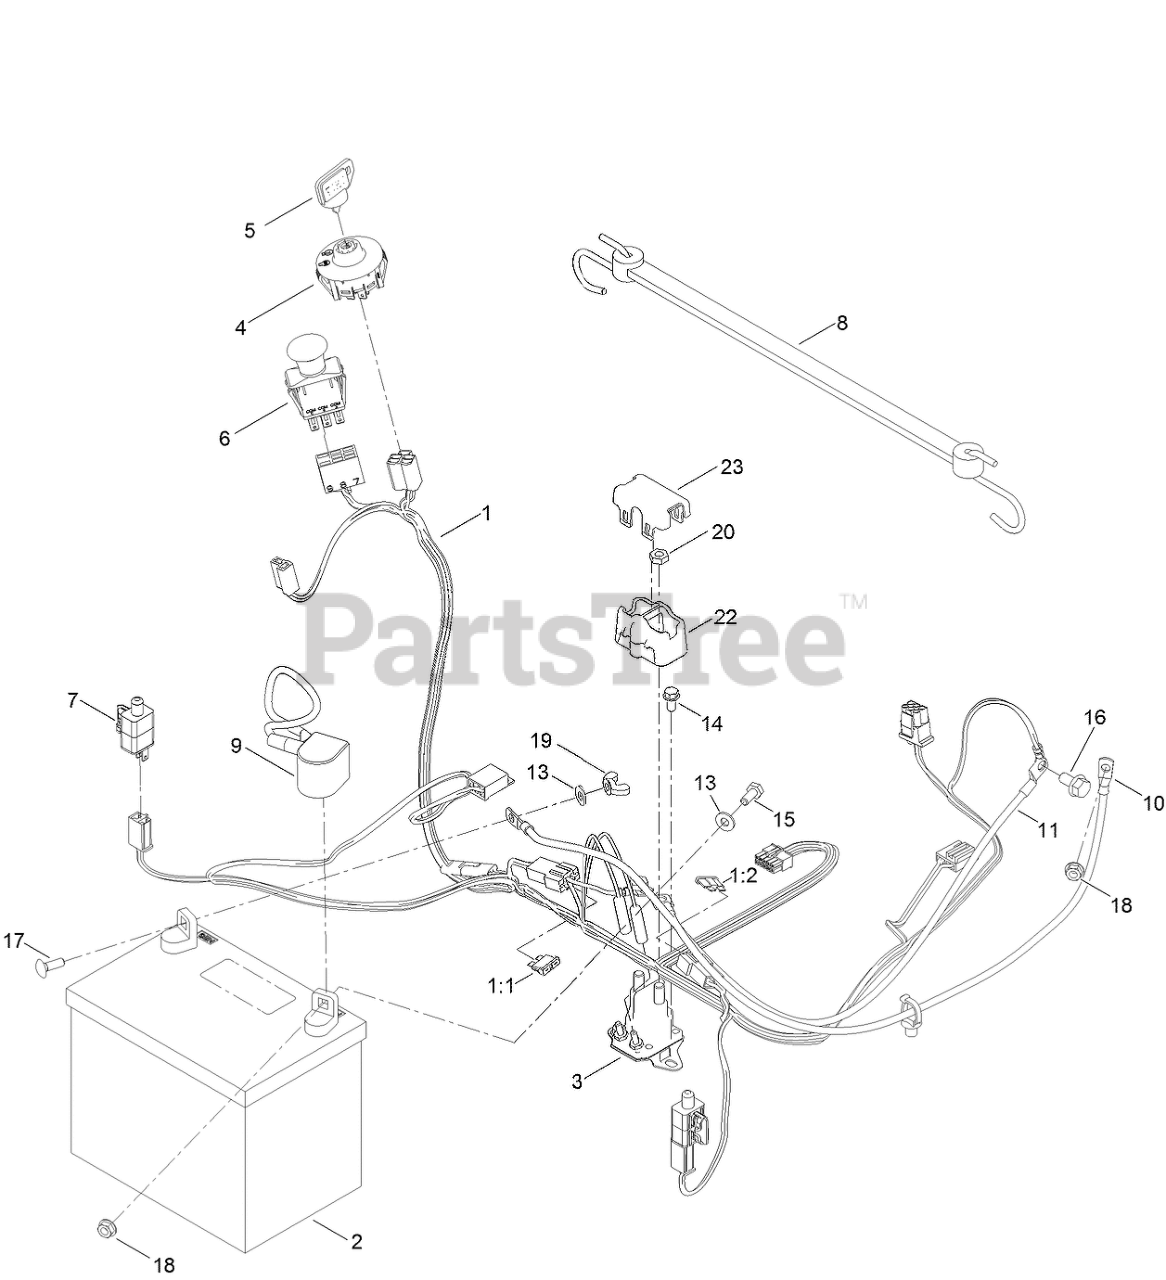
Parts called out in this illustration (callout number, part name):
1	HARNESS-WIRE
1:1	FUSE-BLADE, 15 AMP
1:2	FUSE-BLADE, 25 AMP
2	BATTERY
3	SOLENOID
4	SWITCH-IGNITION
5	KEY-IGNITION
6	SWITCH-PTO
7	SWITCH
8	STRAP-RUBBER
9	CABLE-BATTERY, POS
10	CABLE-BATTERY, RED (8 GAUGE)
11	CABLE-BATTERY, BLACK
13	WASHER-FLAT
14	SCREW-HWH
15	SCREW-HH
16	SCREW-HHF
17	BOLT-CARR
18	NUT-HF
19	NUT-WING
20	NUT-JAM
22	COVER-SOLENOID
23	CAP-SOLENOID
